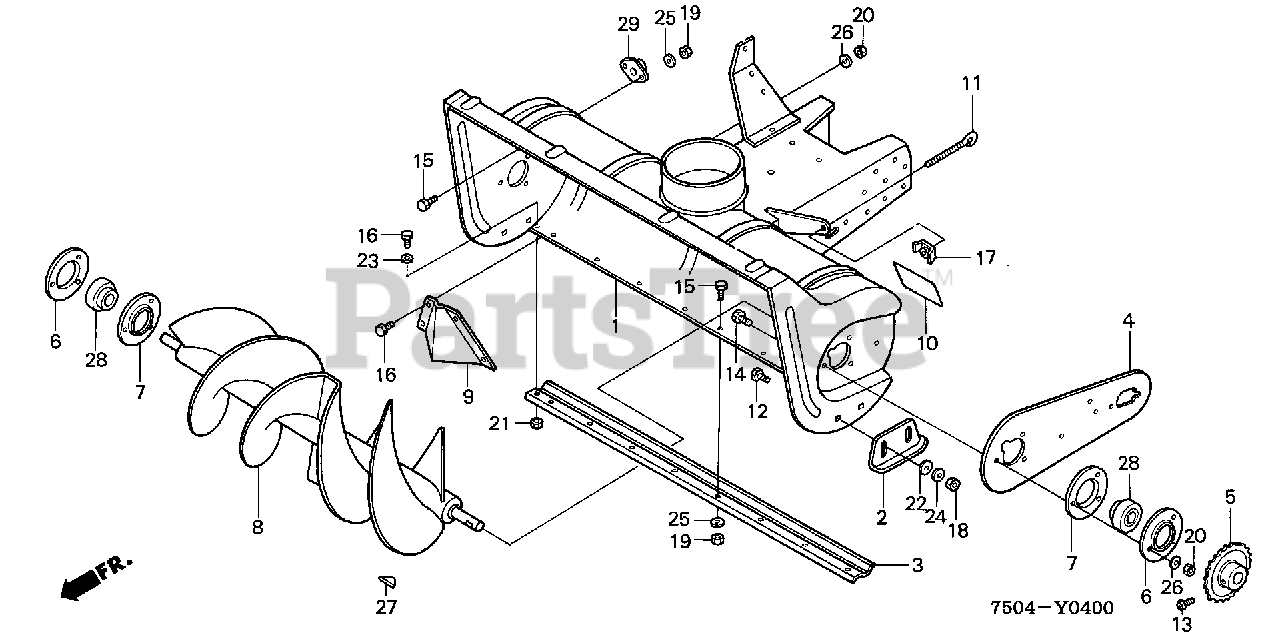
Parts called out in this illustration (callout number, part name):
1	BODY, SNOW THROWER
3	SCRAPER, BODY
4	PLATE, SIDE
5	SPROCKET, ROTOR
6	FLANGE, BEARING
7	FLANGE, BEARING
8	ROTOR ASSY.
10	LABEL, SNOW THROWER BODY
11	BOLT, TENSIONER
12	BOLT, CARRIAGE (3/8-16X3/4)
13	SCREW, SETTING (5/16-18X5/16)
14	BOLT, HEX. (5/16-18X3/4)
15	BOLT, HEX. (1/4-20X5/8)
16	BOLT, HEX. (5/16-18X5/8)
17	NUT, ADJUSTING
18	NUT, HEX. (3/8-16)
19	NUT, HEX. (1/4-20)
20	NUT, HEX. (5/16-18)
21	NUT, HEX. LOCK (5/16-18)
22	WASHER (3/8")
23	WASHER, PLAIN (0.25 INCH)
24	WASHER, LOCK (0.375)
25	WASHER, LOCK (1/4)
26	WASHER, LOCK (5/16)
28	BEARING, CARTRIDGE
